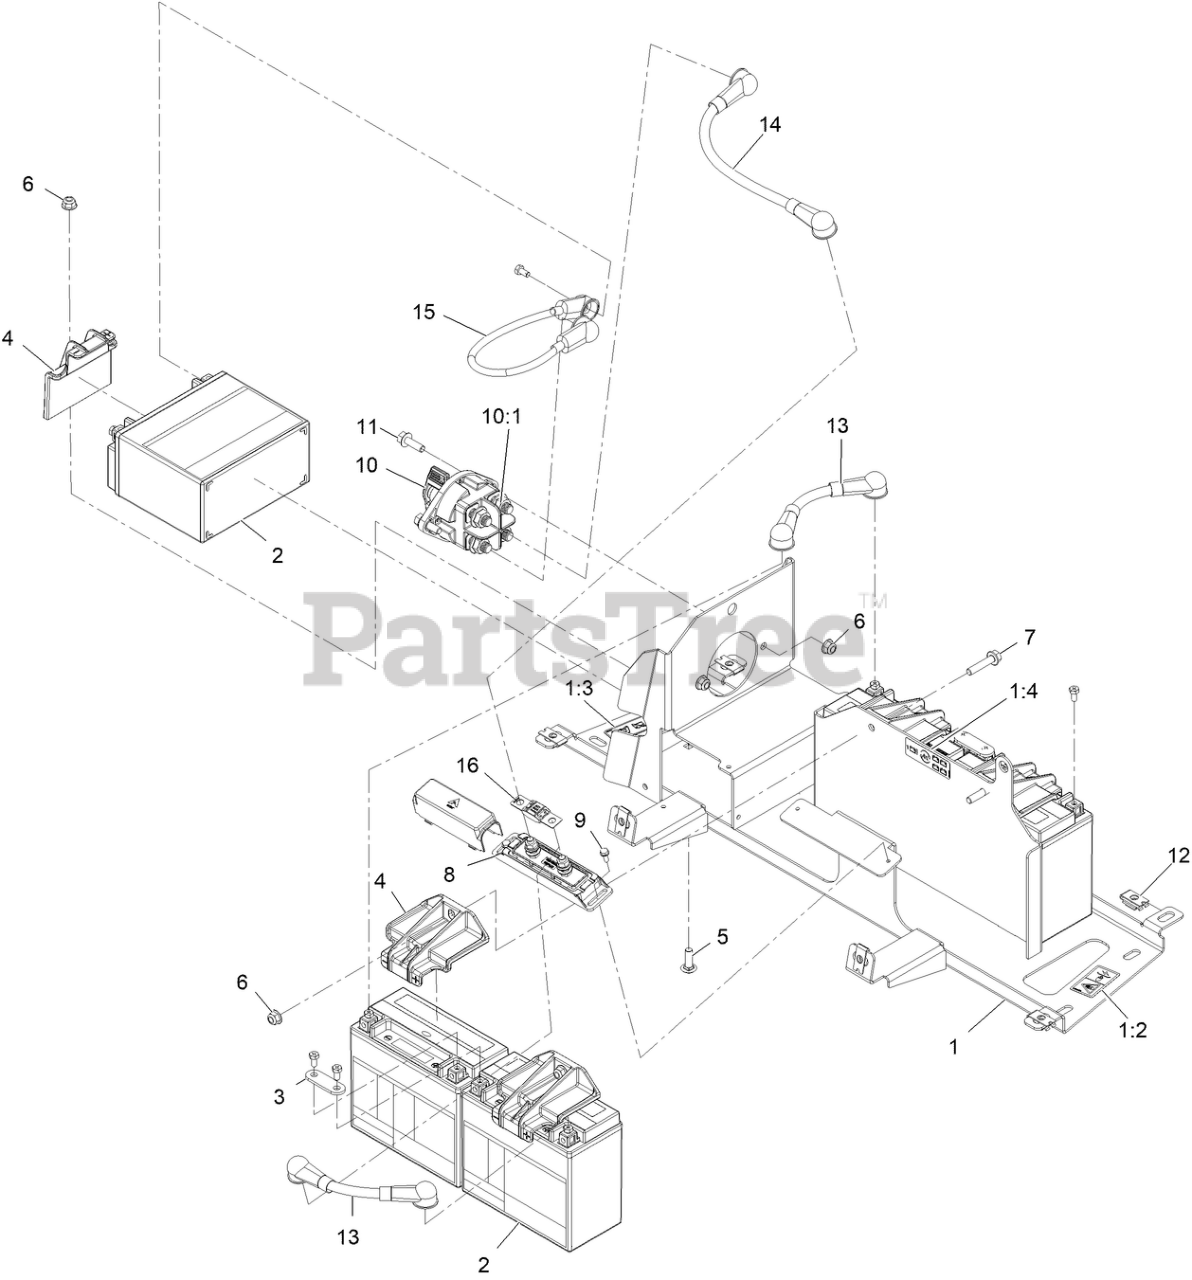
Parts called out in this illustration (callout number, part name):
1	SUPPORT-BATTERY
1:2	DECAL-SHOCK HAZARD
1:3	DECAL-SERVICE, SHUT-OFF
1:4	Decal-Battery Replacement
2	BATTERY-AGM
3	BAR-BUS, 2 POS
4	HOLD DOWN, BATTERY
5	SCREW-CARR
6	NUT-HF, NI
7	SCREW-HHF
8	HOLDER-FUSE
9	SCREW-TAPTITE
10	SWITCH-DISCONNECT
11	SCREW-HHF
12	Nut-Retainer
13	CABLE-BATT, RD ASM
14	CABLE-BATT,RD ASM
15	CABLE-BATT, RD ASM
16	FUSE-150A
